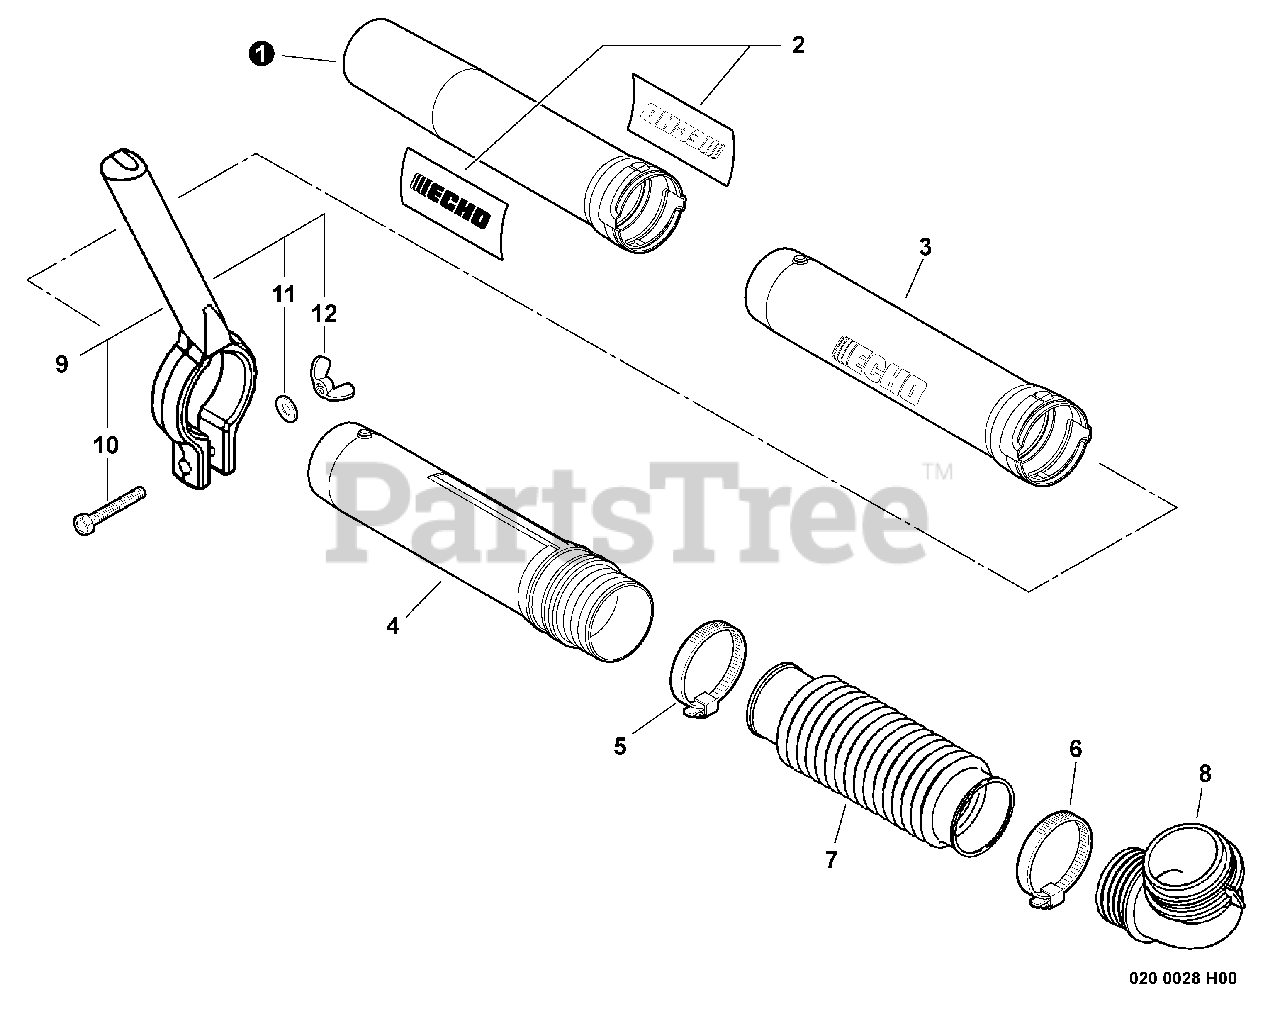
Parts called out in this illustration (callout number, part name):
1	TUBE, BLOWER - NOZZLE
2	LABEL, ECHO BLOWER TUBE
3	TUBE, BLOWER - STRAIGHT
4	TUBE, BLOWER - SWIVEL
5	CLAMP 58.7 MM / 82.5 MM
6	CLAMP - BAND
7	TUBE, FLEXIBLE
8	TUBE, BLOWER - ELBOW
9	HANDLE ASSY, PB LARGE
10	BOLT 6×45
11	WASHER 6.5×11.5×0.8
12	NUT, WING 6
